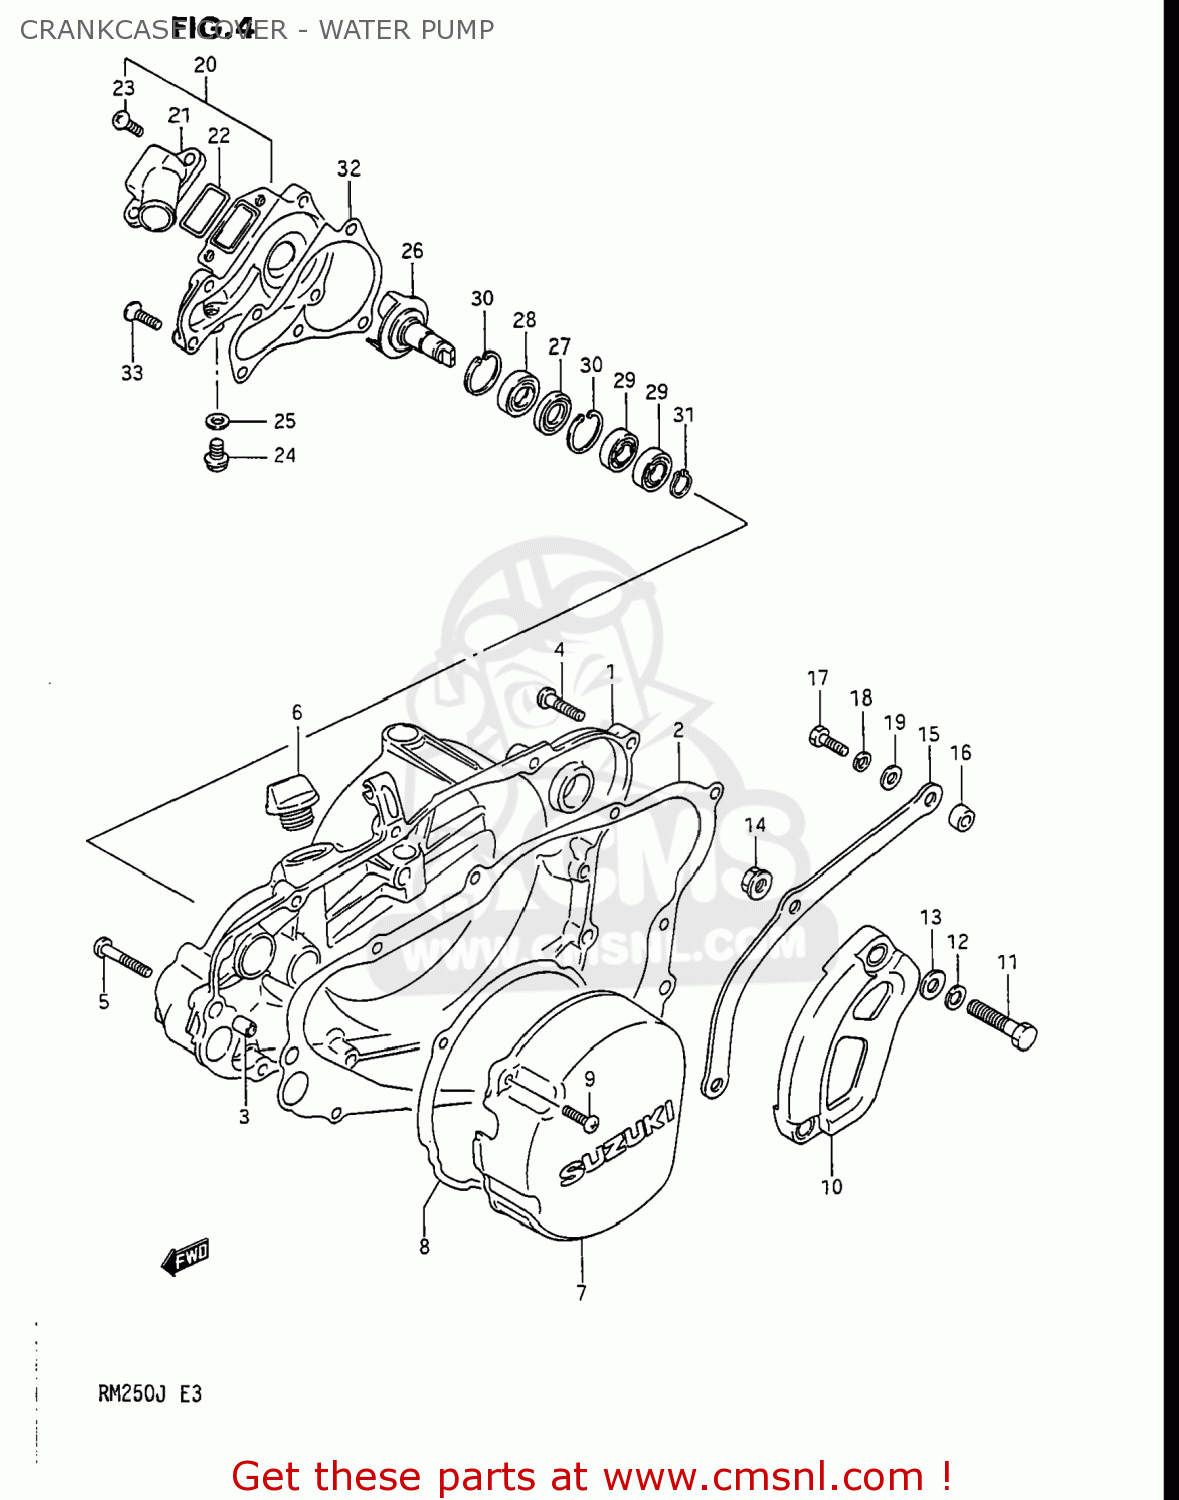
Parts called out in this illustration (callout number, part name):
1	COVER,CLUTCH
2	GASKET,CLUTCH COVER
3	PIN
4	SCREW
5	SCREW
6	PLUG SET
7	COVER,MAGNETO
8	GASKET,MAGNETO COVER (MCA)
9	SCREW
10	COVER,SPROCKET
11	BOLT
12	LOCK WASHER
13	WASHER
14	NUT
15	PLATE,FRONT CHAIN GUIDE
16	SPACER (6.5X12X8)
17	BOLT
18	WASHER,LOCK
19	WASHER
20	CASE ASSEMBLY,WATER PUMP
21	CONNECTOR,WATER INLET
22	O RING,WATER PUMP CONNECTOR
23	SCREW
24	BOLT,DRAIN
25	GASKET 8.2X14X1 (NAS)
26	IMPELLER,WATER PUMP
27	SEAL,OIL(12X24X3.6)
28	SEAL,OIL(12X24X6.4)
29	BEARING(10X22X6)
30	CIRCLIP
31	CIRCLIP,10MM
32	GASKET,WATER PUMP CASE (MCA)
33	SCREW
